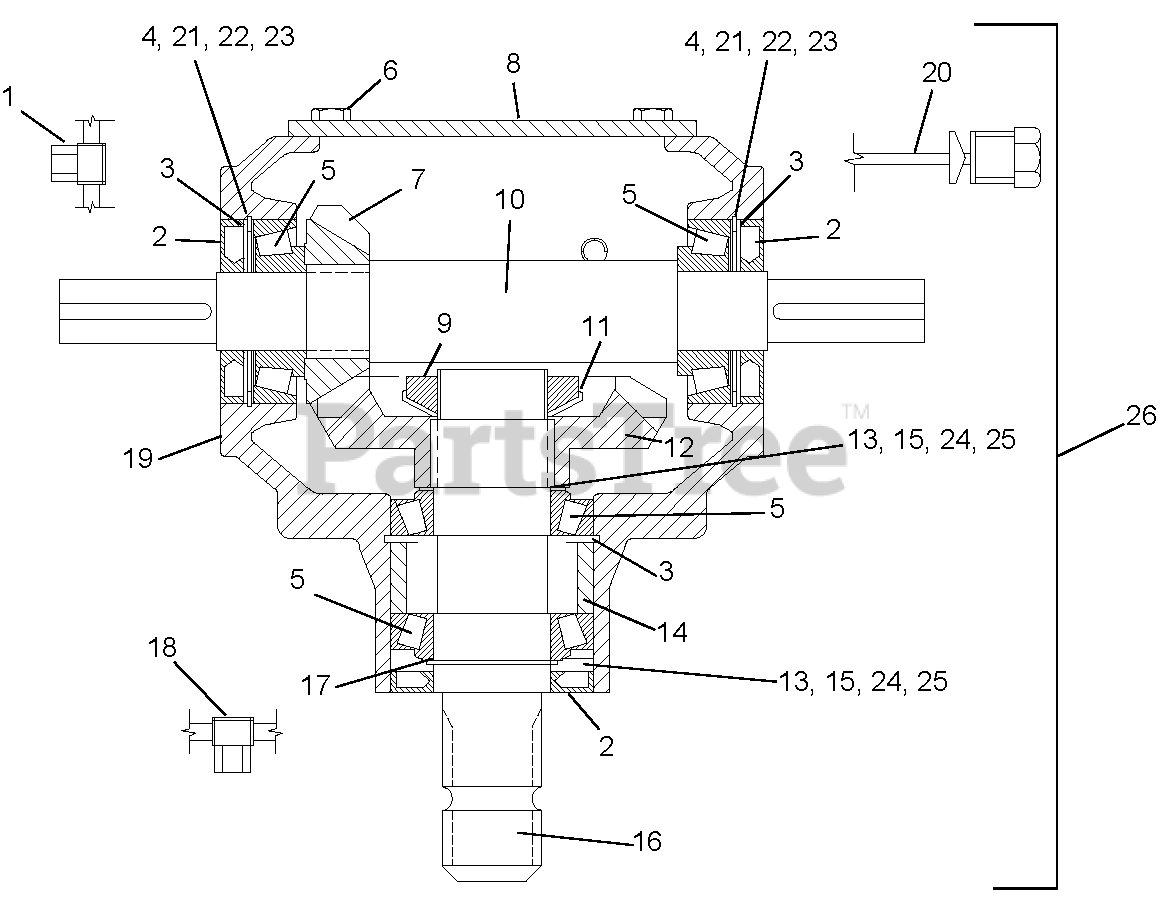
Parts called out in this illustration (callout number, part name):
1	Oil Plug
2	Seal, Oil 36 x 72 x 10
3	Snap Ring, UN17437
4	Shim, 60.3 mm I.D. x 71.7 mm O.D.
6	Bolt, M8 x 14
7	Pinion Z15 M 5 7
9	Nut, Lock M35 x 1.5
11	Washer, Spring
12	Wheel, Crown Z22 M5 7
13	Shim 35.3 mm I.D. x 48 mm O.D. x 1.3 mm
15	Shim 35.3 mm x 48 mm x .5 mm
16	Shaft 1.375 In.
17	Snap Ring 35
18	Plug .25
19	Casing, T3
20	Plug, Oil Level
21	Shim 60.3 mm x 71.7 mm x .3 mm
22	Shim 60.3 mm x 71.7 mm x .4 mm
23	Shim 60.3 mm x 71.7 mm x .5 mm
24	Shim 35.3 mm x 48 mm x .3 mm
25	Shim 35.3 mm x 48 mm x .4 mm
26	Gearbox Assembly
